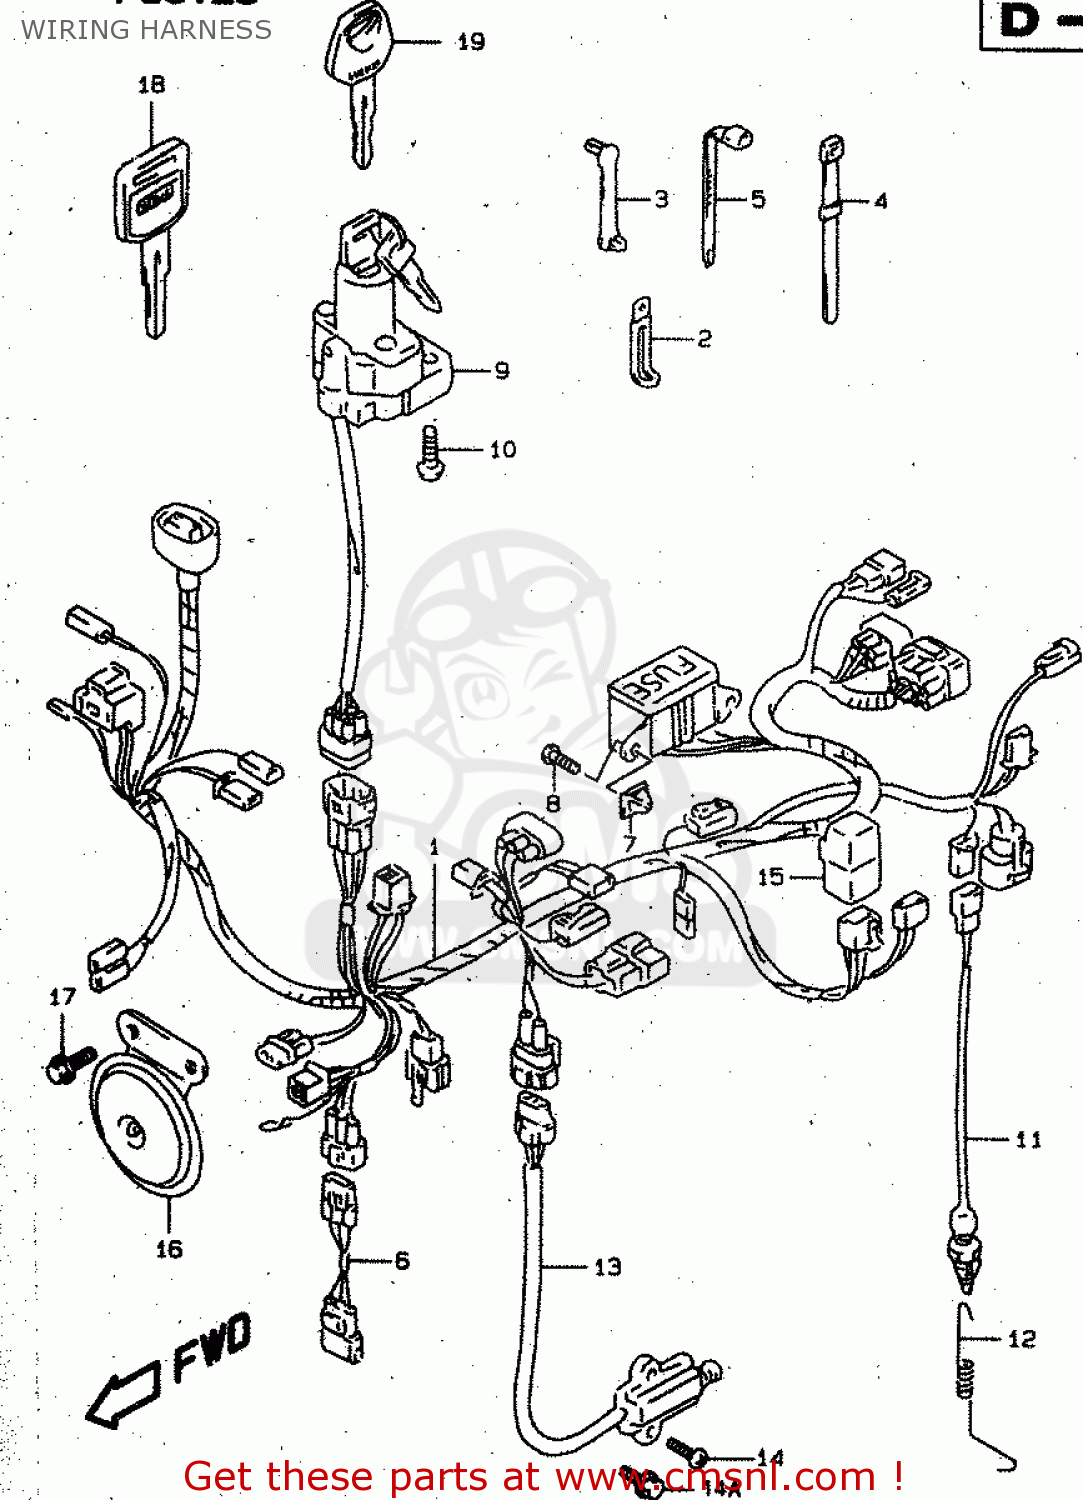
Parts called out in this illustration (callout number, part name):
1	HARNESS,WIRING
2	CLAMP(L:65)
3	CLAMP(L:33)
4	CLAMP(L:120)
5	CLAMP(L:125)
6	WIRE,THROTTLE SENSOR
7	NUT
8	SCREW
9	LOCK ASSY,STEERING
10	BOLT(8X20)
11	SWITCH ASSY,STOP LAMP
12	SPRING
13	SWITCH ASSY,SIDE STAND
14	SCREW 6X16
14A	BOLT
15	RELAY ASSY
16	HORN ASSY
17	BOLT
18	KEY,BLANK
19	KEY,BLANK
